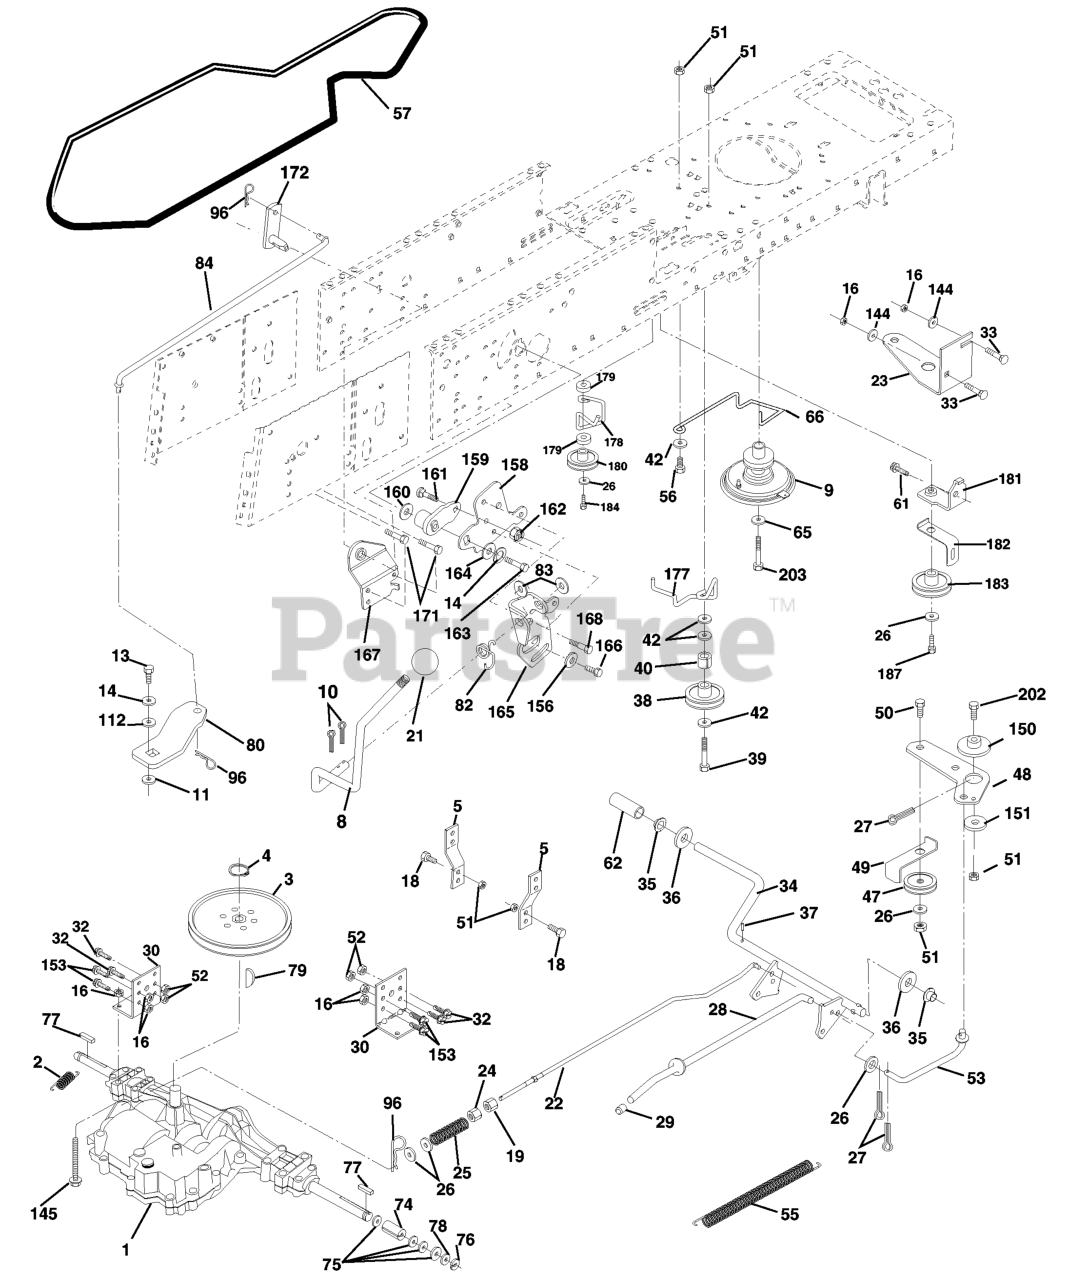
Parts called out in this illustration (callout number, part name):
2	SPRING,BRAKE RETURN
3	PULLEY
4	RETAINING RING LT
5	STRAP TORQUE
8	ROD.SHIFT.FENDER.ADJ.LT.CRD
9	CLUTCH ASSY
10	PIN COTTER
11	WASH-SHFT PLT LT
13	BOLT 1/4-28X3/4
14	LOCKWASHER
16	NUT.71038.31-18.HEX.NYLOCK
18	BOLT
19	NUT
21	KNOB.DUCKHEAD.1/2
23	Bracket Clutch Noram
24	NUT
25	SPRING ROD LT
26	WASHER
27	COTTER PIN
28	ROD BRAKE PARK LT
29	PLUNGER CAP
30	BRACKET TRANSAXLE
32	BOLT
33	RP BOLT 5/16-18 X3/4 ZN/YEL GR
35	BEARING.NYLON
36	WASHER LT
37	DRIVE PIN
38	PULLEY.FLAT
42	WASHER
47	IDLER PULLEY
48	BELLCRANK, CLUTCH
49	RETAIN BELT
50	BOLT
52	LOCKNUT
53	LINK, CLUTCH LT
55	SPRING, RETURN LT
57	V-BELT.KEV.111"
61	SCREW 3/8-16X3/4
62	COVER, PEDAL (1 2)
65	LOCKWASHER
66	KEEPER BELT ENGINE
74	SPACER AXLE
77	SQUARE KEY
79	KEY STD (1373) DANA
82	SPRING,TORSION
83	WASHER
96	RETAINER M
112	WASHER LT
144	Washer 11/32 x 5/8 x 16 Ga.
145	BOLT
150	BUSHING.BELLCRANK.GRD.DR
151	WASHER 12/32X2X10GA
153	BOLT RB
156	WASHER.SRRTD.5/16
158	BRACKET
159	HUB
160	Washer 29/32 x 1-1/4 x 16 Ga.
161	BOLT
162	NUT.CROWNLOCK.1/4
163	BOLT
164	Washer 5/8 x .281 x 10 Ga.
165	RP BRACKET
167	BRACKET.SUPT.SHIFT.CRD
168	BOLT.SHOULDER.5/16-18X
171	SCREW LT
172	SHAFT
180	PULLEY.FLAT.IDLER
181	BRKT.IDLER.GRD.DR.CRD
182	KEEPER BELT
183	PULLEY.V-IDLER
184	SCREW.HXWSH.3/8
187	SCREW
202	BOLT.3/8-16X1.50
203	BOLT.HEX.7/16-20 X 5
